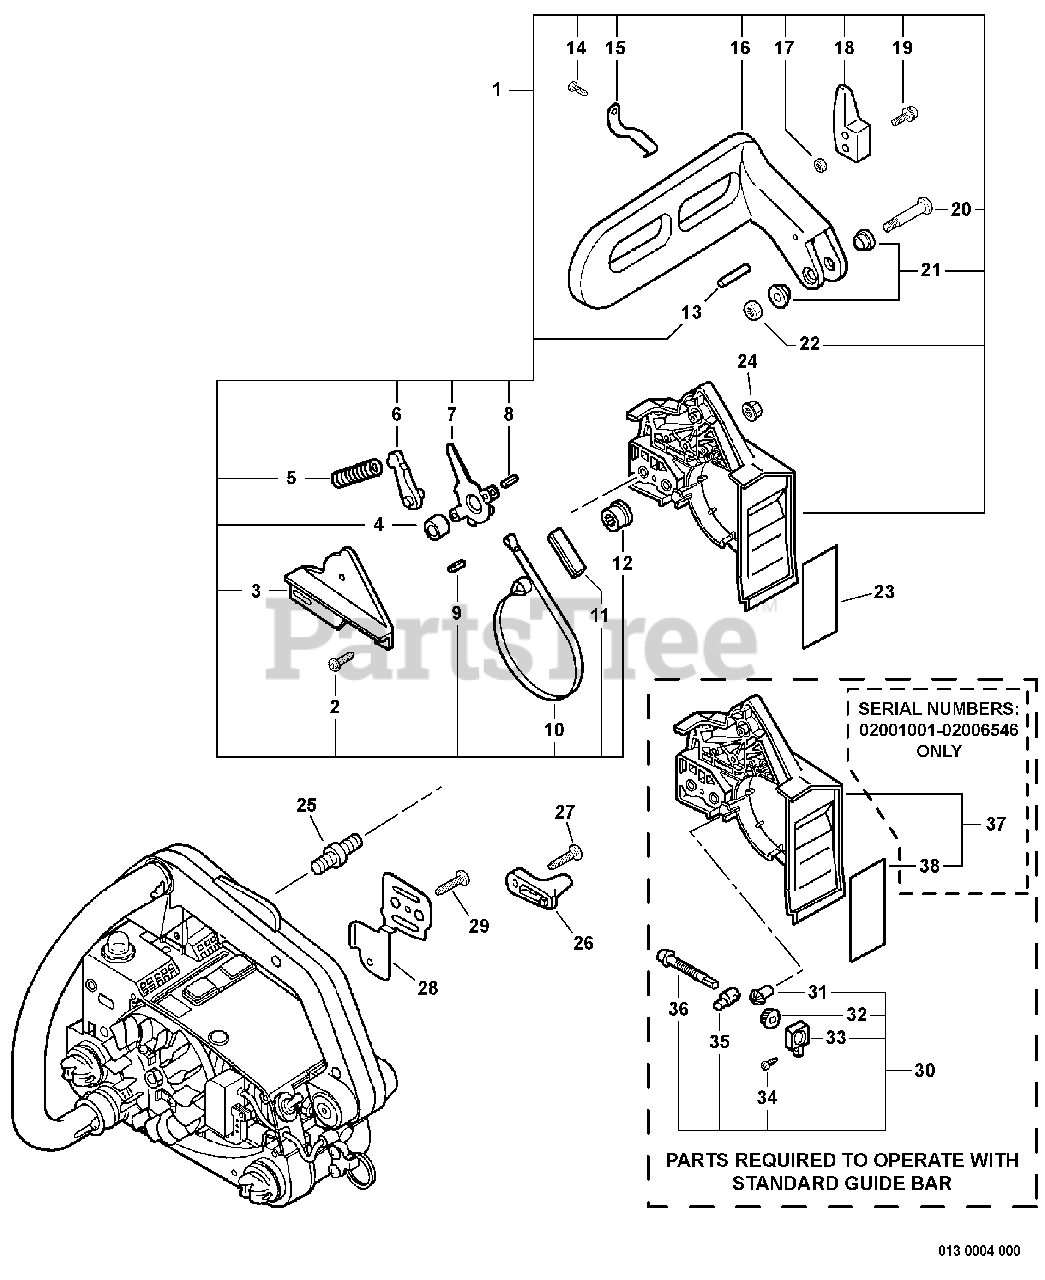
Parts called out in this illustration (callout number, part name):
1	CHAIN BRAKE ASSY
2	SCREW 4×12
3	COVER, BRAKE
4	SPACER 8×12×9
5	SPRING, COMPRESSION
6	STOPPER, BRAKE
7	LEVER, BRAKE
8	PIN, SPRING 4×8.8
9	PIN, SPRING 2.5×12
10	BAND, BRAKE
11	SEAL, BRAKE
12	ADJUSTER, BRAKE
13	ROLLER 4×23.8
14	SCREW 4×10
15	SPRING, FLAT
16	LEVER, BRAKE
18	WEIGHT, BRAKE
19	SCREW 4×20
20	SCREW 5×32
21	COLLAR 5.3×10×13×L5
22	NUT, LOCK M5
23	SHIELD, HEAT 35×60×0.10
24	NUT, FLANGE M6
25	BOLT, STUD 6
26	CHAIN CATCHER
27	SCREW, TAPPING 5×20
28	PLATE, GUIDE
29	SCREW 4×10
30	SIDE ADJUSTER KIT
31	GEAR, BEVEL
32	GEAR, BEVEL
33	COLLAR 8
34	SCREW 4×12
35	TENSIONER, CHAIN
36	BOLT 5
37	GUARD, SPROCKET - GRAY
38	SHIELD, HEAT 35×60×0.10
